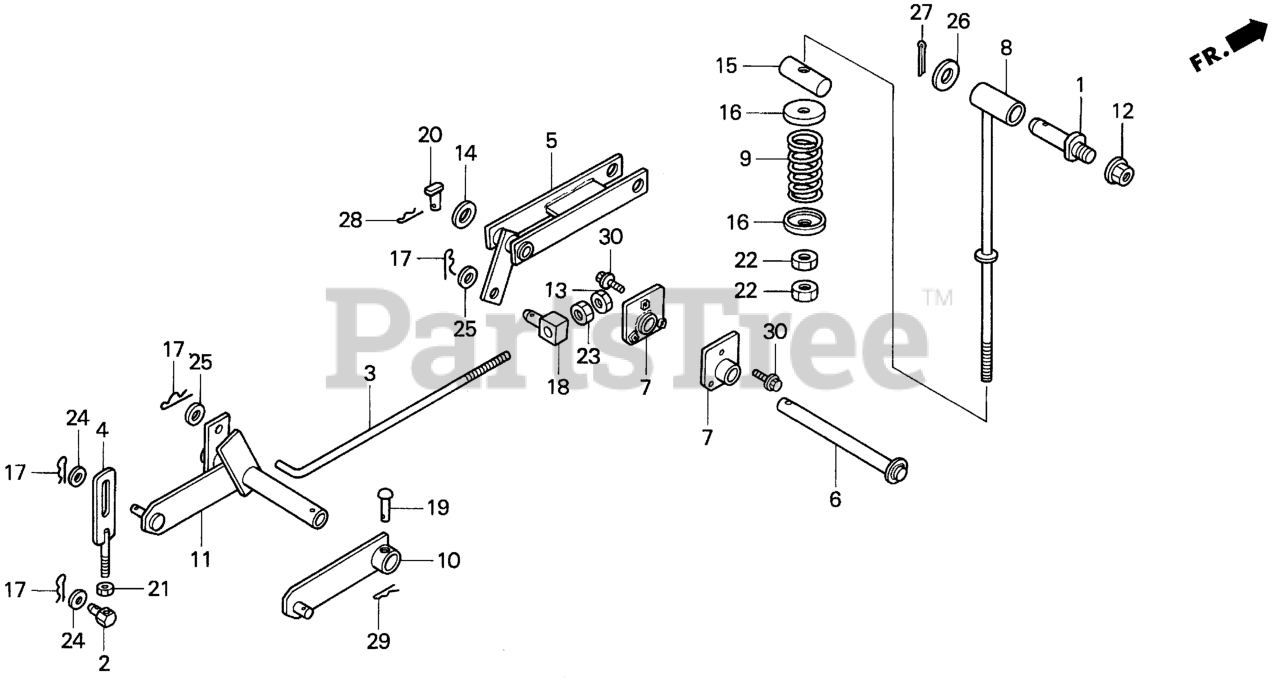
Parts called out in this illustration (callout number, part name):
1	PIN, LIFT ARM
2	PIN, FR. LINK ADJUSTING
3	ROD, CUTTER DECK LIFT
4	PLATE, CUTTER DECK LIFT
5	LINK, CUTTER DECK LIFT
6	SHAFT, LIFT LINK
7	PIVOT, LIFT LINK
8	ROD, LIFT LINK
9	SPRING, LIFT DAMPER
10	ARM, R. LIFT
11	ARM, L. LIFT
12	NUT, SPECIAL (16MM)
13	NUT, SELF-LOCK (16MM)
14	WASHER, PLAIN (22MM)
15	PIN, DAMPER SPRING
16	WASHER (16MM)
17	PIN, LOCK (14MM)
18	PIN, LIFT ARM
19	PIN, LIFT ARM (10X51.5)
20	PIN, LINK SHAFT (8X28)
21	NUT, HEX. (12MM)
22	NUT, HEX. (16MM)
23	NUT, HEX. (16MM)
24	WASHER, PLAIN (14MM)
25	WASHER, FLAT (16MM)
26	WASHER, FLAT (18MM)
27	PIN, COTTER (3.0X35)
28	PIN, LOCK (8MM)
29	PIN, LOCK (10MM)
30	BOLT, FLANGE (8X20)
